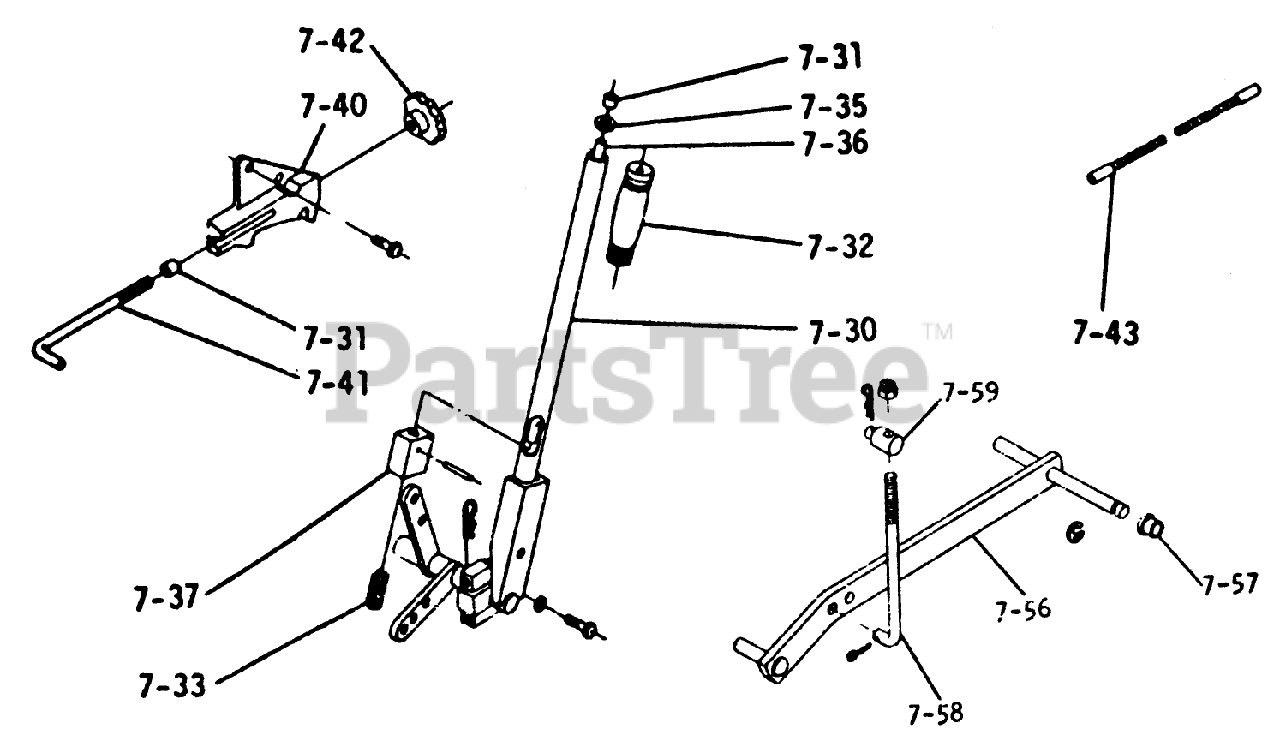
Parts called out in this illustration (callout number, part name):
7-32	HANDGRIP
7-33	SPRING-COMPRESSION
7-42	KNOB-LIFT CONTROL
7-57	BUSHING
7-58	ROD-LIFT
7-59	TRUNNION-LIFT
